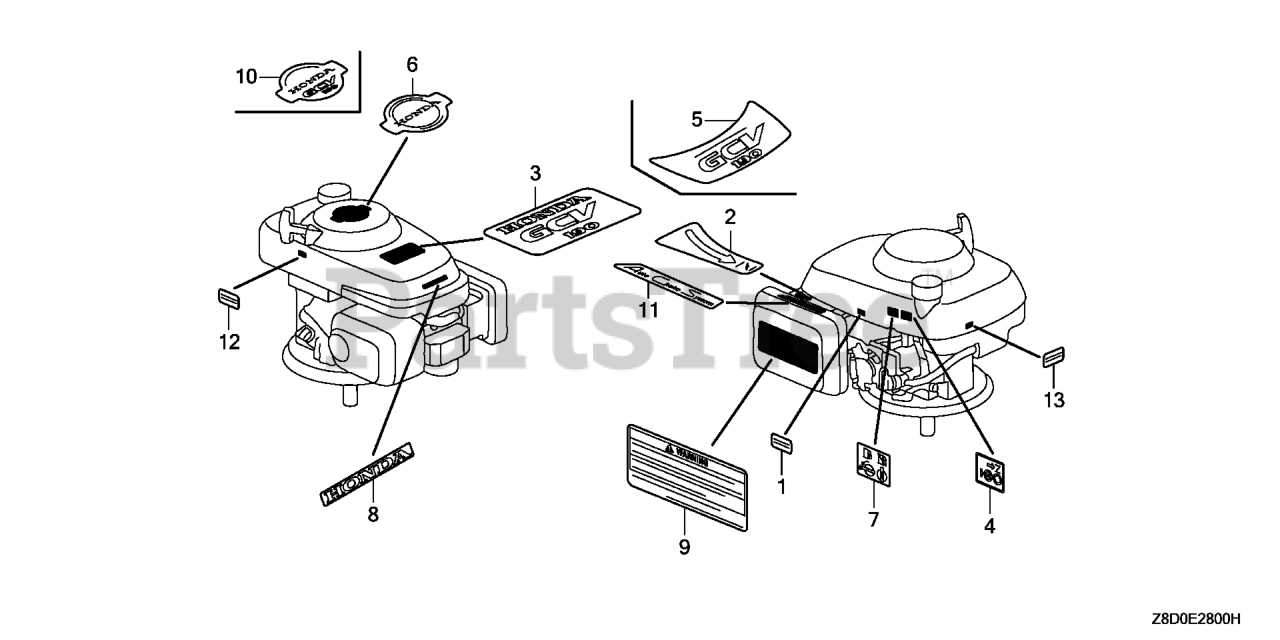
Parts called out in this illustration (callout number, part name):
7	MARK, FUEL PETCOCK CAUTION
9	MARK, OPERATOR CAUTION (ENGLISH)
10	MARK, RECOIL COVER
11	MARK, AUTO CHOKE
12	LABEL, WARNING (NOT CERTIFIED FOR SALE)
